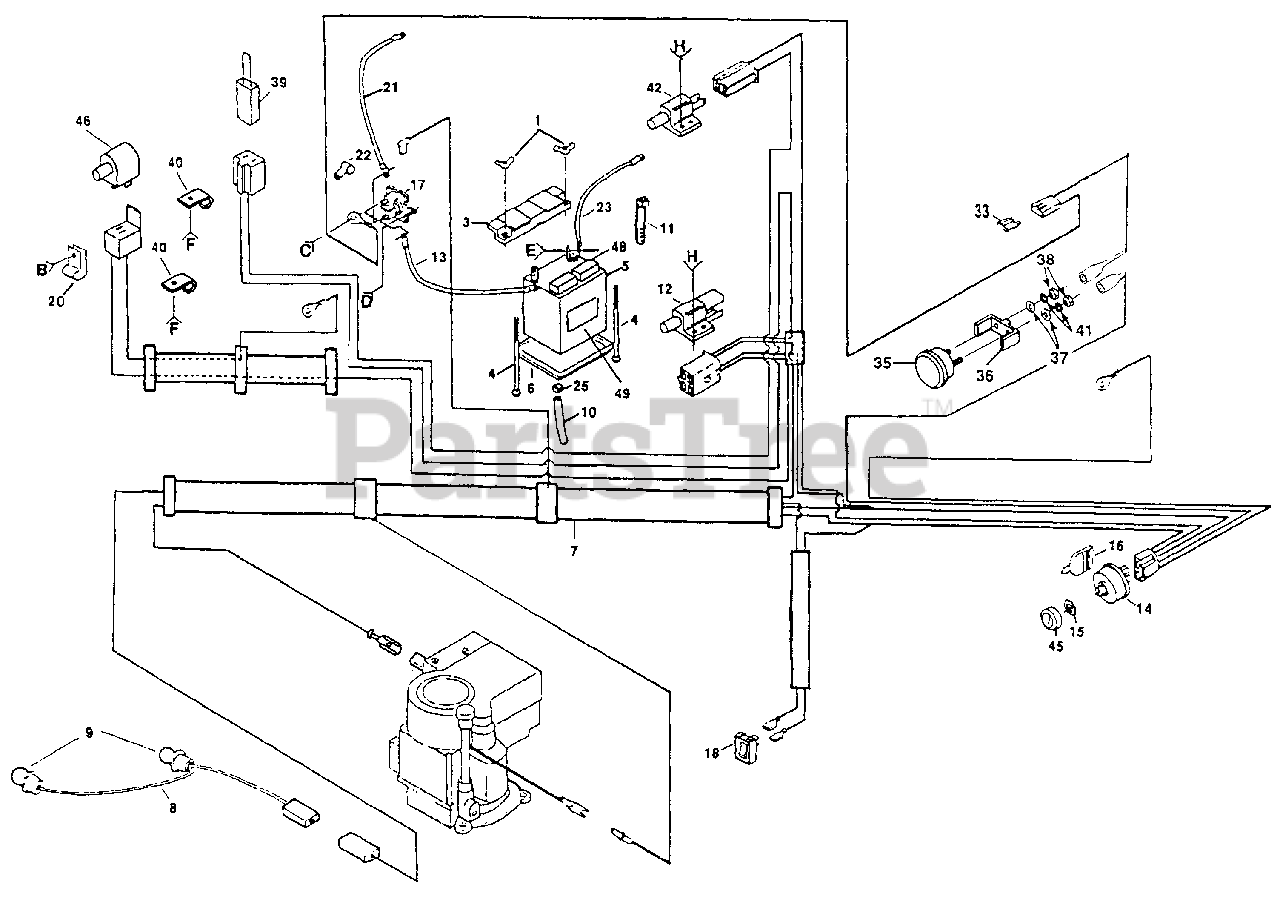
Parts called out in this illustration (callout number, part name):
1	Wing Nut 1/4-20
3	Terminal Guard
4	Carriage Bolt 1/4-20 x 7-1/2
5	Battery 12V.
6	Battery Tray
7	Ignition Harness
8	Harness, Light Socket
9	Light Bulb
10	Tube, Battery Tray
11	Cable Tie
12	Switch, Interlock, Attachment Clutch
13	Cable, Battery (Battery to Solenoid)
14	Switch, Ignition
15	Nut, Ignition
17	Solenoid
18	Switch, Light
20	Clip Wire
21	Cable, Battery (Solenoid to Starter)
22	Terminal Cover (For Solenoid)
23	Cable, Battery (Battery to Ground)
25	Clamp, Hose
33	Fuse, 30 AMP
36	Bracket, Ammeter
37	Washer, 7/32 x 1/2 x 18 Ga.
39	Loop, Wire
40	Clip, Insulated
41	Washer, Lock Ext. 3/4
42	Switch, Interlock, Clutch Pedal
45	Bezel, Ignition
46	Switch, Plunger
48	Battery Caps Set
49	Decal, Battery Caution
